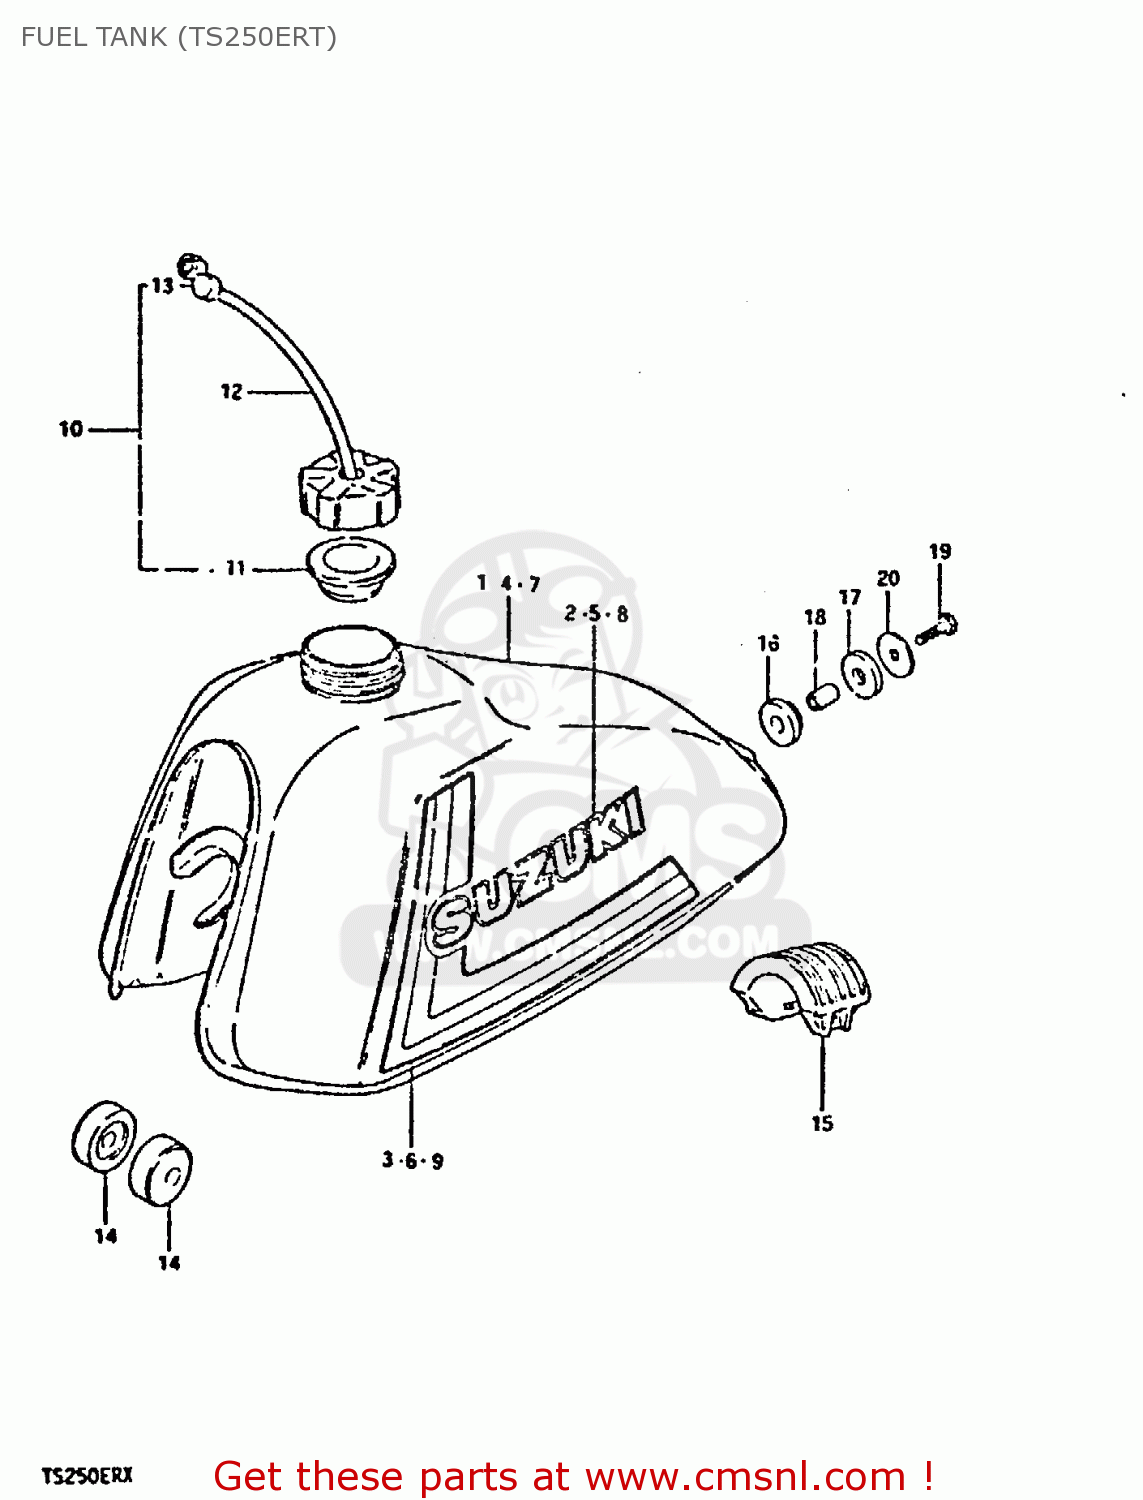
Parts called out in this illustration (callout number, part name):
1	TANK, FUEL
2	EMBLEM
3	TAPE SET
4	TANK, FUEL
5	EMBLEM(BLACK)
6	TAPE SET
7	TANK, FUEL
8	EMBLEM(BLACK)
9	TAPE SET
10	CAP SET,FUEL TANK
11	GASKET,FUEL TANK CAP (NAS)
12	HOSE
13	CLAMP,FUEL TANK BREATHER HOSE
14	CUSHION
15	CUSHION,FUEL TANK
16	CUSHION
17	CUSHION
18	SPACER (8.2X12X17)
19	BOLT (8X30)
20	WASHER (8.5X29X1.6)
